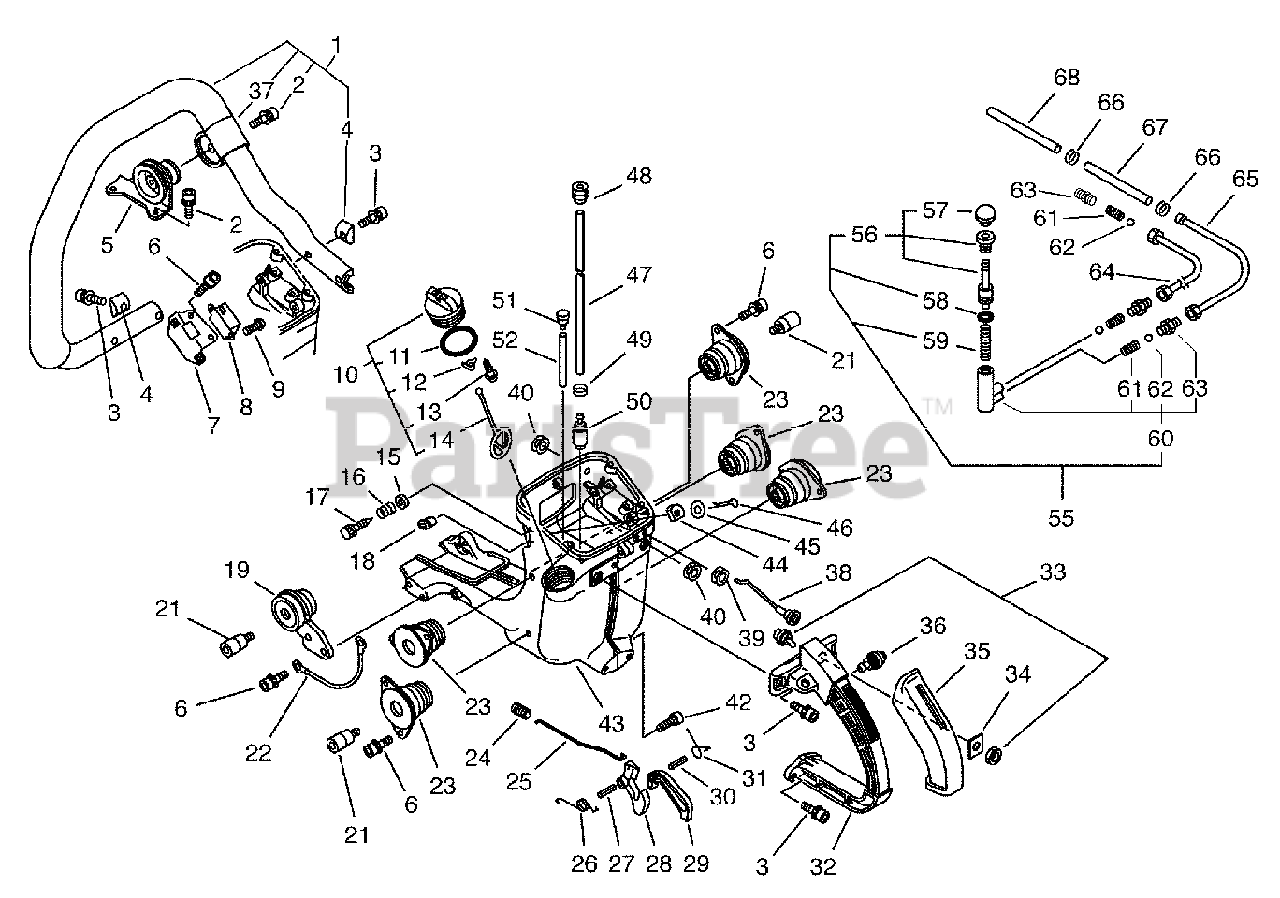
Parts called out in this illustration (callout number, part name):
1	HANDLE KIT - FRONT
2	SCREW - 6X20
3	SCREW - 6X25
5	CUSHION (L-U)
6	SCREW - 5X14
7	BRACKET, MODULE
8	MODULE, E.S.G.
9	SCREW - 5X10
10	CAP ASSY
11	O-RING - 32
12	RETAINER
13	SCREW - 3X8
14	CONNECTOR, CAP
15	WASHER - 4
16	SPRING
17	SCREW, IDLE ADJUST
18	GROMMET
22	LEAD - GROUND
24	GROMMET
25	ROD, THROTTLE
26	SPRING, TRIGGER
27	PIN - SPRING -- 5X25
28	TRIGGER, THROTTLE
29	LOCKOUT, THROTTLE
30	PIN - SPRING -- 4X18
31	SPRING, LOCKOUT LEVER
33	IGNITION SWITCH KIT
34	LABEL - SWITCH
36	LATCH, THROTTLE
37	BRACKET, HANDLE
38	ROD, CHOKE
40	BUSHING
42	SCREW - 5X14
43	TANK, FUEL
44	SEAL, FELT
45	WASHER - 2
46	PIN, SPLIT -- 2X15
47	PIPE - 3X6X360
49	CLIP - 6.5
50	FILTER, FUEL
51	VENT, FUEL TANK
52	PIPE
55	OIL PUMP ASSY
56	PISTON, OIL PUMP
57	BUTTON, PUSH
58	O-RING - 6
59	SPRING, OIL PUMP
60	OIL PUMP BODY ASSY
61	SPRING, VALVE
62	VALVE, BALL
63	CONNECTOR
67	PIPE - FUEL
68	TUBE, PROTECTIVE
